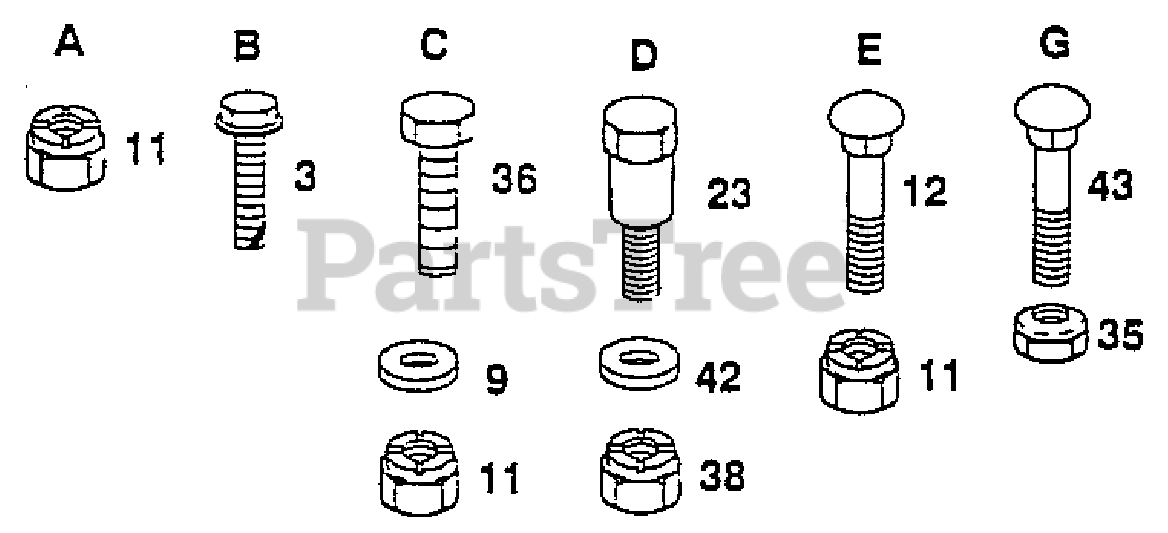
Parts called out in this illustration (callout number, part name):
3	Screw, Tap. Hex Hd. #10-24 x 11
9	Washer 13/32 x 13/16 x 12 Gauge
11	Nut, Crownlock 3/8-16
12	Bolt, Carriage 3/8-16 x 1
23	Bolt, Shoulder 3/8 x 16
35	Locknut 5/16-18
36	Bolt, Hex 3/8-16 x 1
38	Nut, Centerlock,-Flange 3/8-16
42	Washer, Spring
43	Bolt, Carriage 5/16-18 x 3/4
